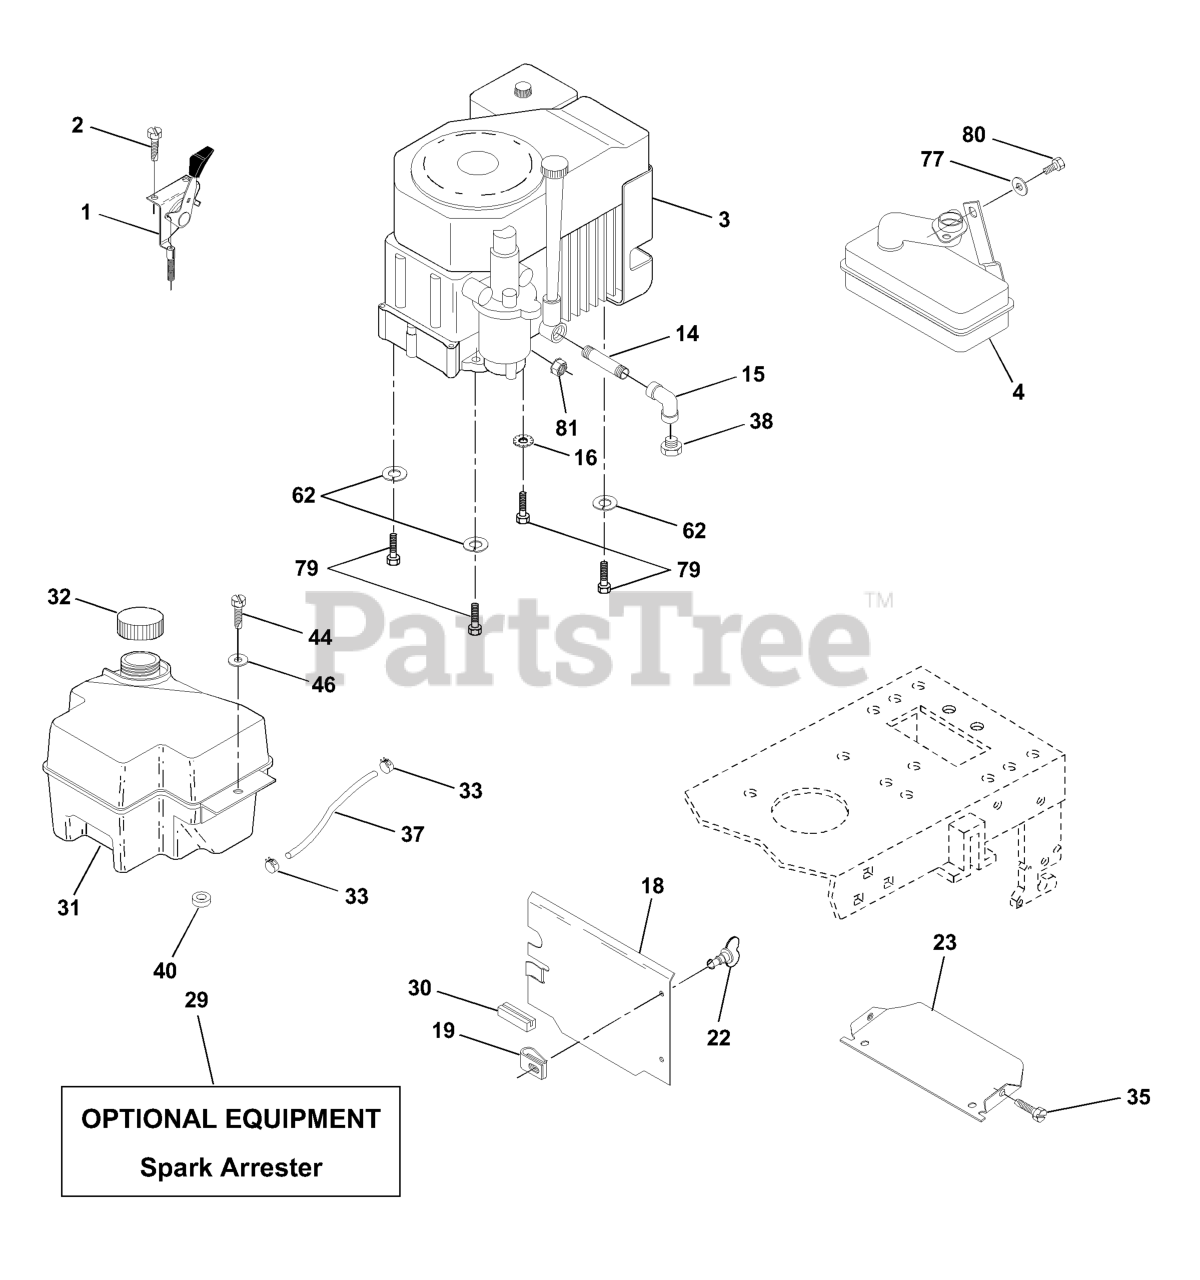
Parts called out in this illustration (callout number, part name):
1	CONTROL SWITCH 27 LH
2	SCREW LT
3	Engine Kohler, Model Number CV15S 13 HP
4	MUFFLER LT 12.5
14	Nipple Pipe 3/8 Npt X 3-1/2
15	ELBOW
16	WASHER EXT TOOTH LOCK 5/16
18	HEAT SHIELD
19	RECEPTACLE LT
22	STUD 1/4 TURN
23	Shield Heat Browning LT/YT
29	KIT.SPARK ARRESTOR 794945 B&S
31	FUEL TANK
32	FUEL CAP
33	HOSE CLAMP
35	SCREW.THDROL.5/16-18X3/4.TTY
37	LINE.FUEL.20
38	Plug Oil Drain
40	BUSHING.SNAP.NYL.BLK.
44	SCREW HEX CRT
46	WASHER
62	WASHER.LOCK.HVY.HLCL.SPR.5/16
77	WASHER
79	BOLT, HEX
80	Bolt Hex Hd 5/16-18 UNC x 1/2
81	NUT FLANGE 1/4-20 STARTER NUT
